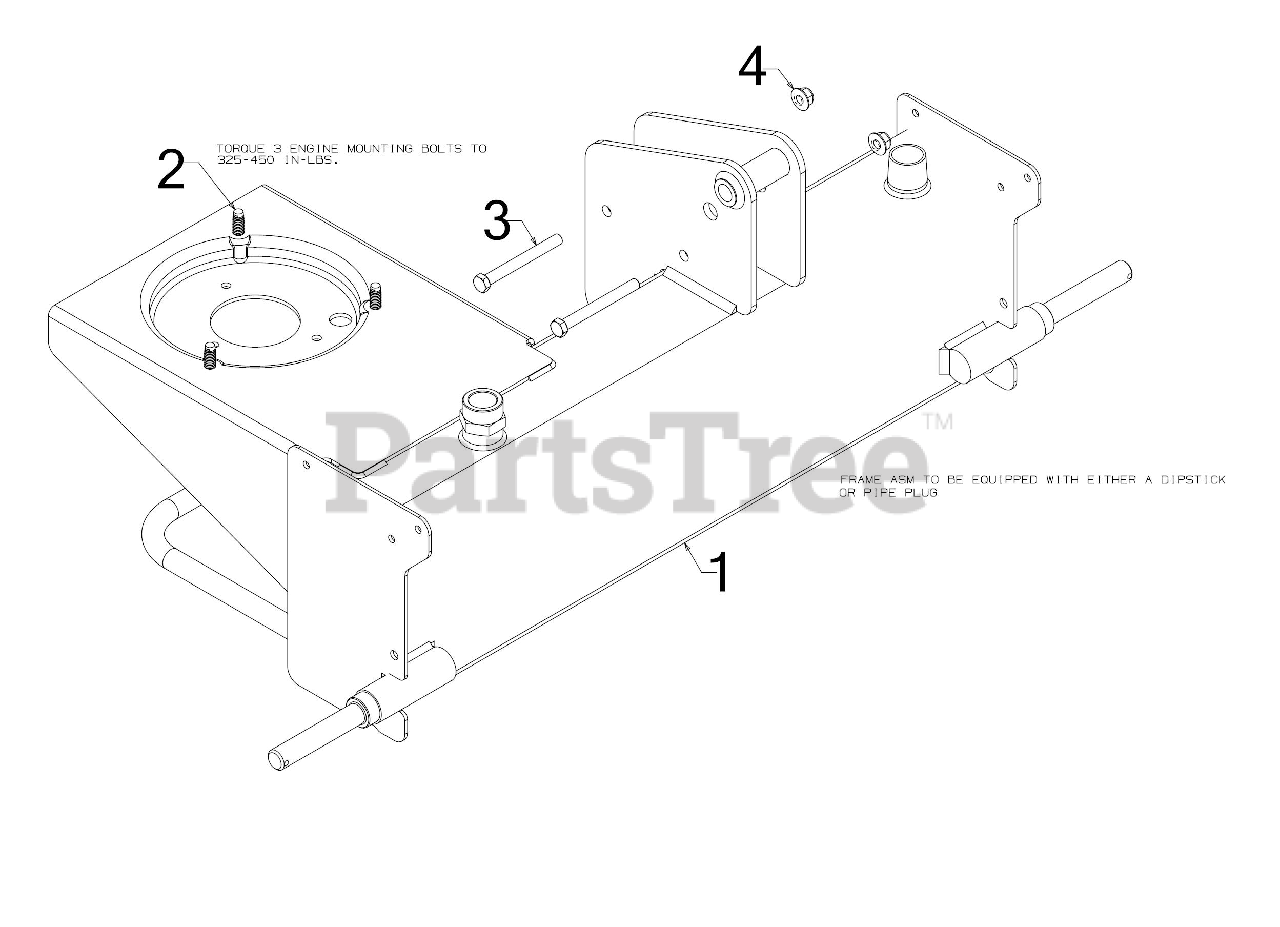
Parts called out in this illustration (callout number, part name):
1	TANK ASSEMBLY
2	SCREW 3/8-16 x 1
3	SCREW 3/8-16 x 3.50 GR5
